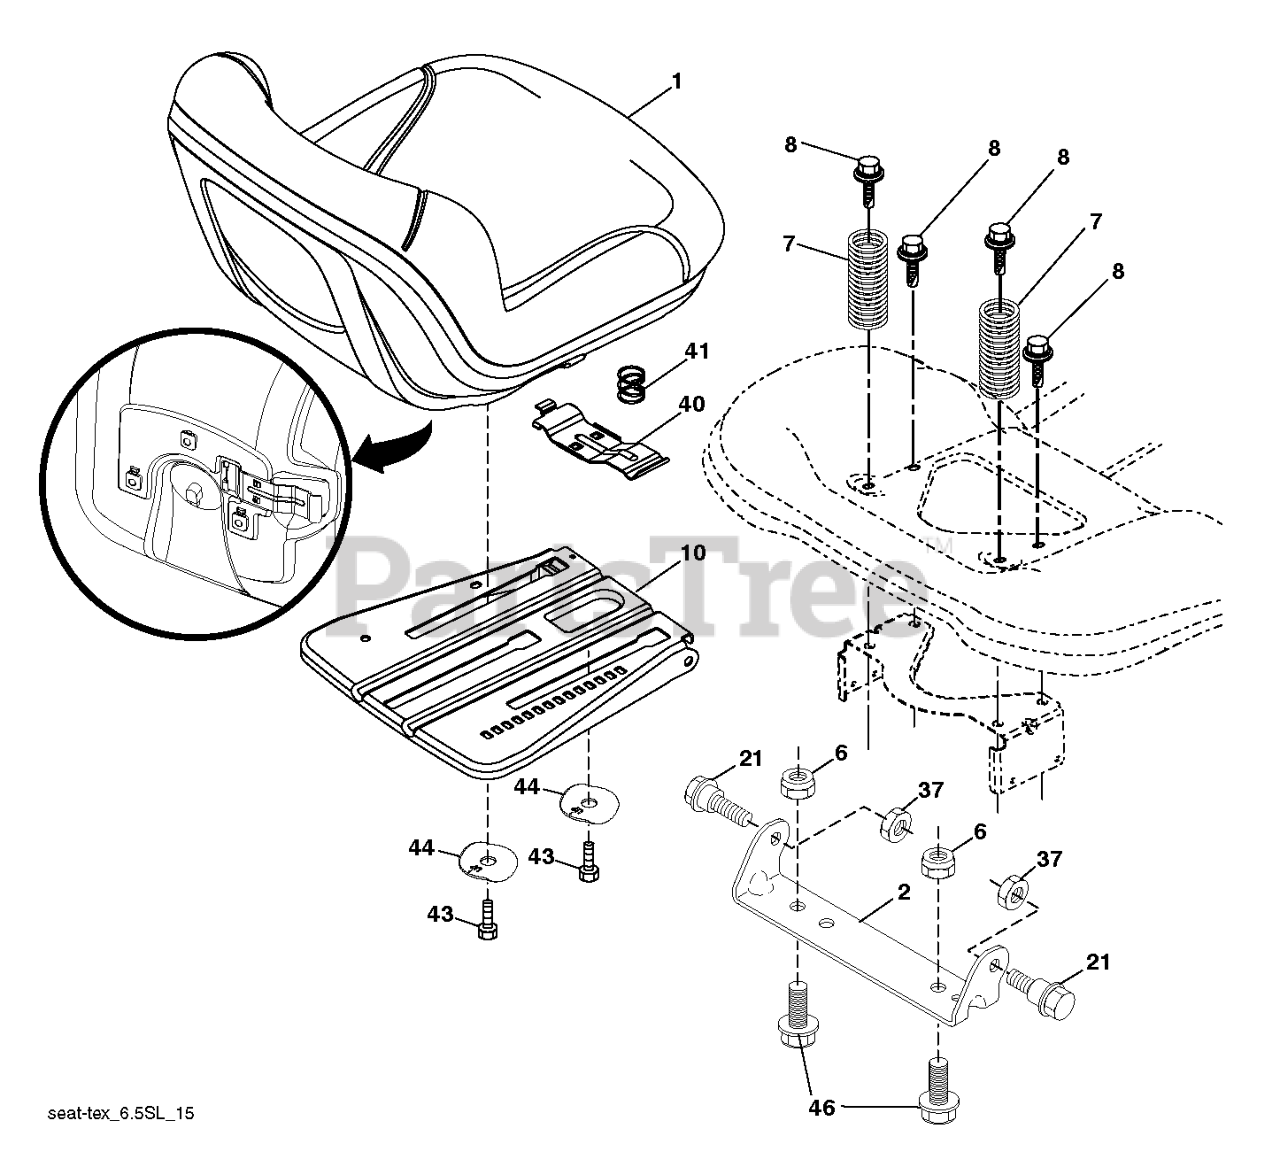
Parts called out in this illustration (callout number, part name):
1	SEAT.TP130.BLK.PPRO.MILSCO
2	BRKT.PIVOT.FENDER
6	Nut, Lock, Hex with Wsh Insert 3/8-16 UNC (AYP part number)
7	SPRING.COMPRESS.SEAT.TAPERED
8	BOLT, 5/16-18 X 1 3/4
10	PLATE.PNT.SEAT.SLIDE.3PT.EDIP
21	BOLT.5/16-18X5/8.SHOULDER
37	Locknut, Hex, with Washer Insert 5/16-18 (AYP part number)
40	HANDLE.SLIDE.SEAT.TEX.BLACK
41	SPRING.LATCH.SEAT.TEX
43	Bolt, Hex,Washer Thread Rolling 3/8 (AYP part number)
44	WASHER.WINGED.3/8ID.1.5OD
46	BOLT.3/8-16X1;1.25OD.WSHR.SEMS
